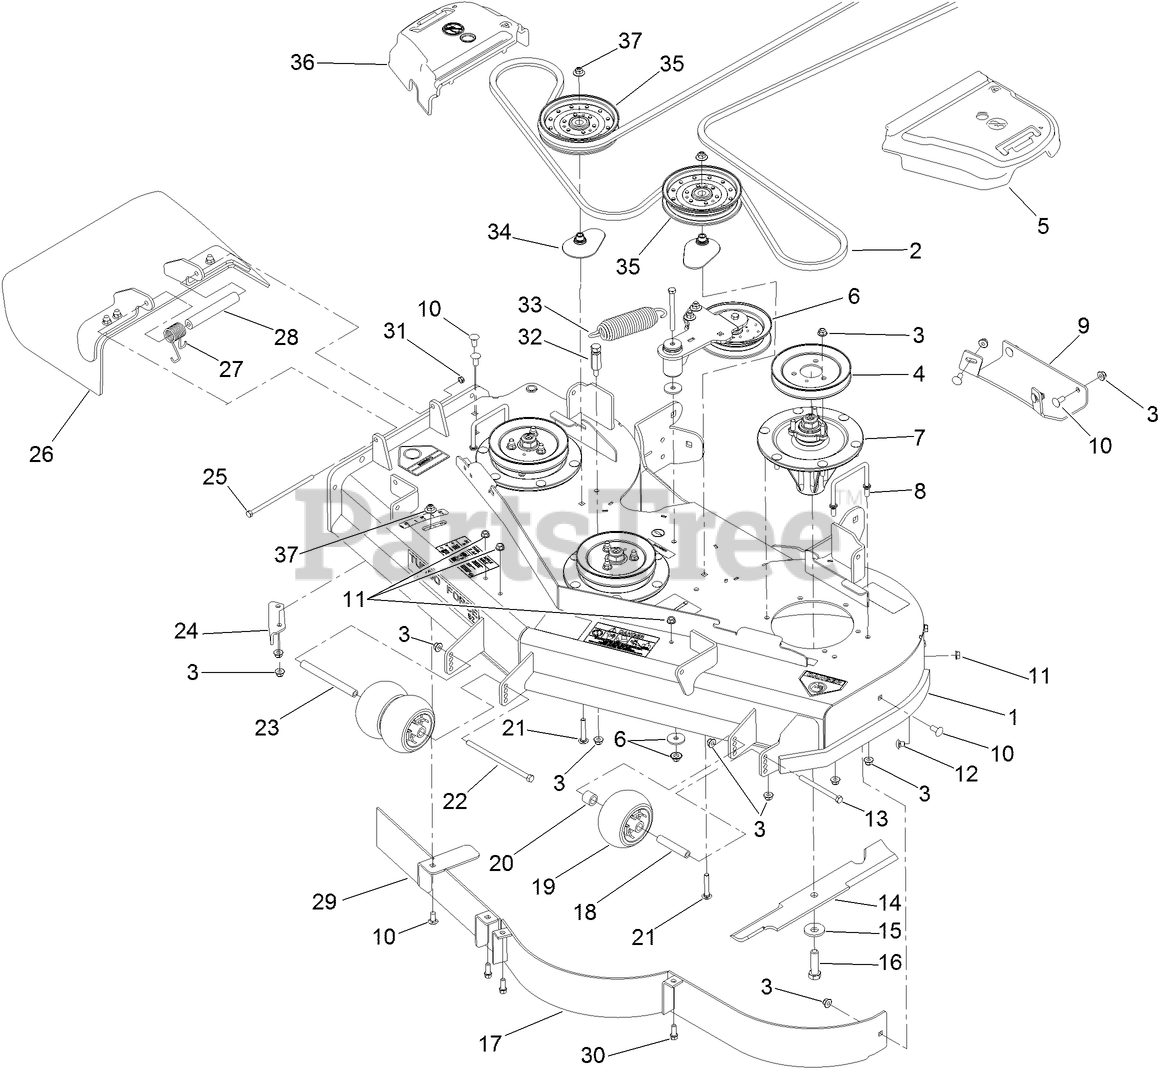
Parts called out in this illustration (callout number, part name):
1	DECK DECAL ASM
2	BELT-V
3	NUT-HF, NI
4	PULLEY
5	COVER-BELT, LH
6	IDLER ARM ASM
7	SPINDLE ASM
8	WIREFORM-COVER
9	PLATE-SKID
10	SCREW-CARR
11	NUT-HHF, WHIZ
12	SCREW-CARR
13	SCREW-HH
14	BLADE-18IN, HI FLOW
15	Washer-Blade Bolt, Heavy
16	SCREW-BLADE
17	BAFFLE ASM
18	TUBE-SPANNER
19	ROLLER-SCALP, ANTI
20	TUBE-SPACER
21	BOLT-CARR, SHORT NECK
22	SCREW-HH
23	SPACER-WHEEL
24	BAFFLE-DISCHARGE
25	SCREW-HH
26	RUBBER DEFLECTOR ASM
27	SPRING-TORSION
28	SPACER
29	BAFFLE ASM
30	SCREW-HWH
31	NUT-LOCK, NI
32	ANCHOR-SPRING, TALL
33	EXTENSION-SPRING
34	SPACER-PULLEY
35	PULLEY-IDLER, FLAT
36	COVER-BELT, RH
37	NUT-FLANGE, NI
